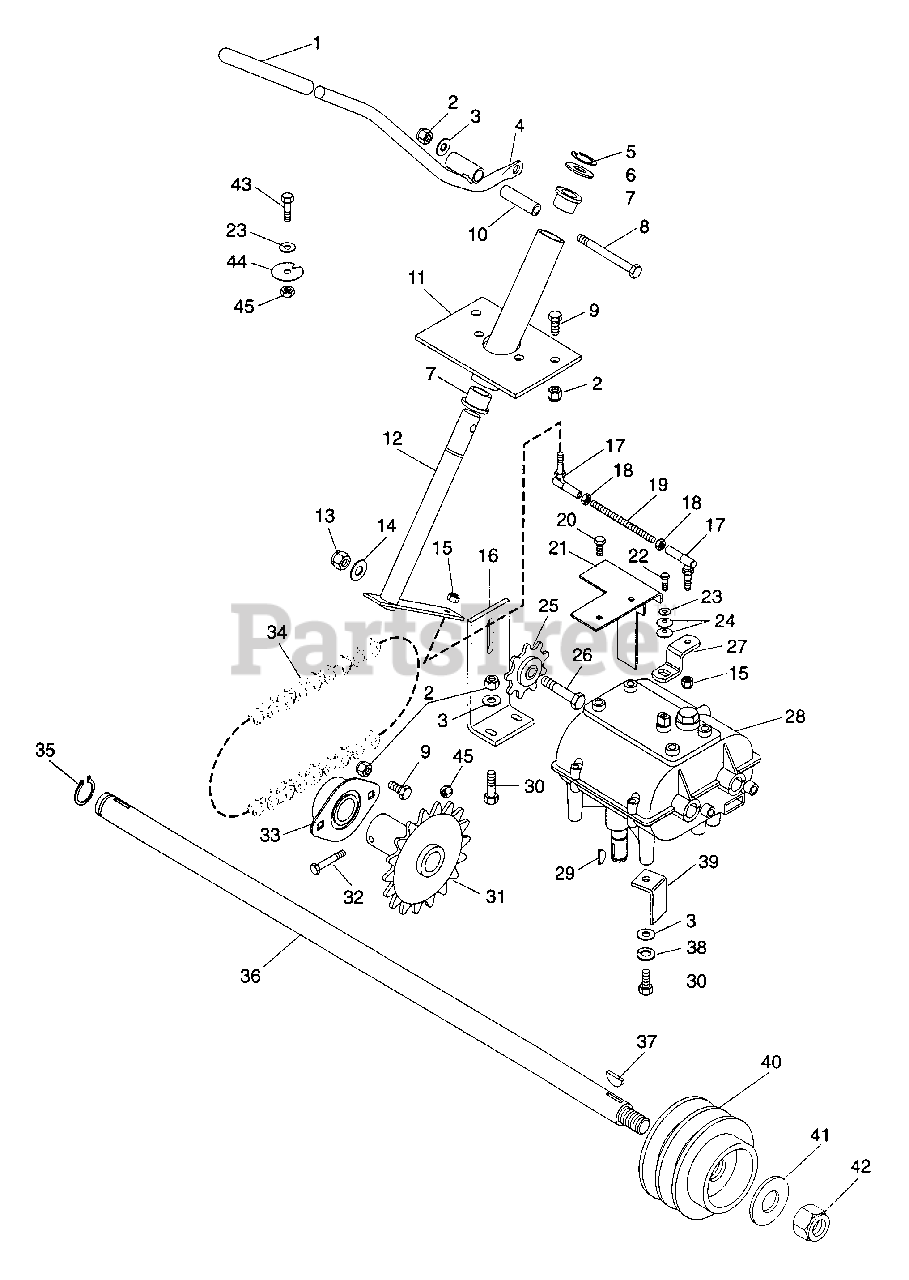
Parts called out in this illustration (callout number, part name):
1	Grip, PTO Lever
2	Nut-Locking-Nylon .312-18 Grade 2
3	Washer-Flat-Steel .344 x .688 x .065
4	Weldment, Shift Lever
5	Ring-Retaining-External .689 x .077
6	Bearing-Needle-Thrust .752 x 1.24 x .031
7	Bushing-Flange .762 x 1.0 x .580 x 1.48
8	Bolt-Hex .31-18 x 2.75
9	Bolt-Hex .31-18 x .75 Grade 5
10	Bushing, Steel .328 x .497 x 1.53
11	Weldment, Shifter Tube
12	Weldment, Shifter Shaft
13	Nut-Locking-Nylon .375-16
14	Washer-Flat-Steel .406 x .812 x .065
15	Nut-Locking-Center .250-28 Grade 2
16	Bracket, Idler Sprocket
17	Ball, Joint Disconnecting
18	Nut .250-28
19	Rod, Transmission Shifting
20	Bolt-Tapping .312-18 x .62
21	Guard, Chain
22	Bolt-Hex .25-28 x .75 Grade 8
23	Washer-Flat-Steel .281 x .62 x .065
24	Washer, Belleville
25	Sprocket, Idler
26	Bolt-Hex .38-16 x 1.75 Grade 5
27	Arm, Transmission Shift
28	Transmission, Pro Line
29	Key, Woodruff .19 x .75
30	Bolt-Hex .31-18 x 1.00 Grade 5
31	Weldment, 28T 1/2 P Sprocket
32	Bolt-Hex .25-20 x 2.25 Grade 8
33	Bearing-Flange 1.000 x 2.125 x .6875
34	Chain, No. 40
35	Ring-Retaining-External .984 x .042
36	Shaft, Jack
37	Key, Woodruff .25 x 1
38	Washer-Lock .313 x .078
39	Guard, V-Belt
40	Pulley, Jack Shaft
41	Washer-Flat-Steel .813 x 1.370 x .100
42	Nut-Locking-Jam-Nylon .75-10
43	Bolt-Hex .25-20 x .63
44	Washer, Flat Notched
45	Nut-Locking-Nylon .250-20 Grade 2
